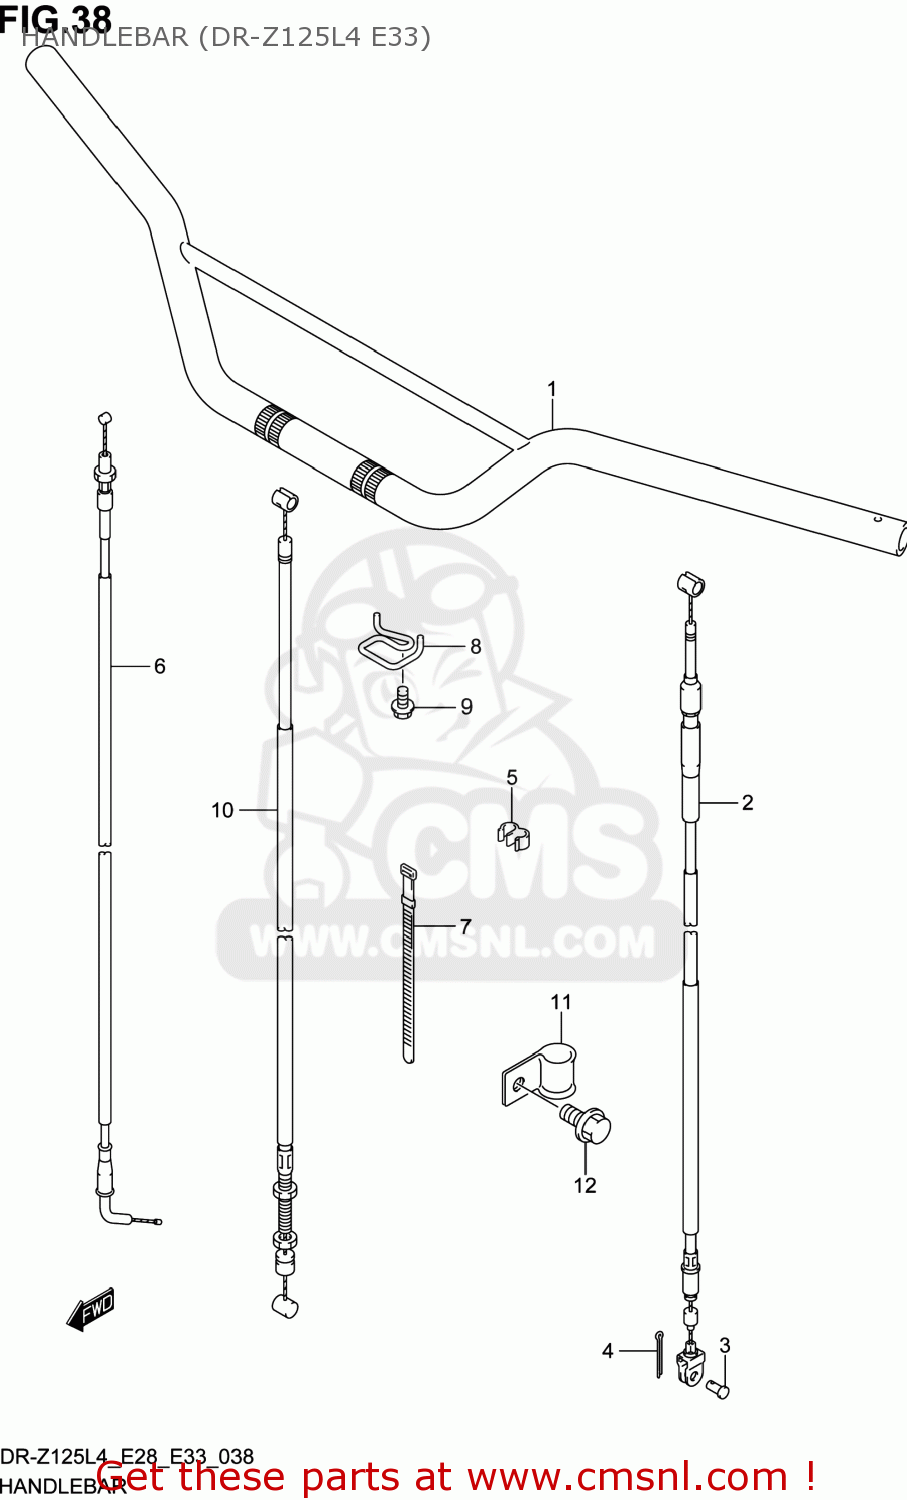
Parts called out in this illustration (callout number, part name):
1	HANDLEBAR(SILVER)
2	CABLE ASSY,CLUTCH
3	PIN(L:13)
4	PIN
5	CLAMP
6	CABLE ASSY,THROTTLE
7	CLAMP(L:90)
8	GUIDE,CABLE
9	BOLT
10	CABLE,FR BRAKE
11	CLAMP,FR BRAKE CABLE
12	BOLT
